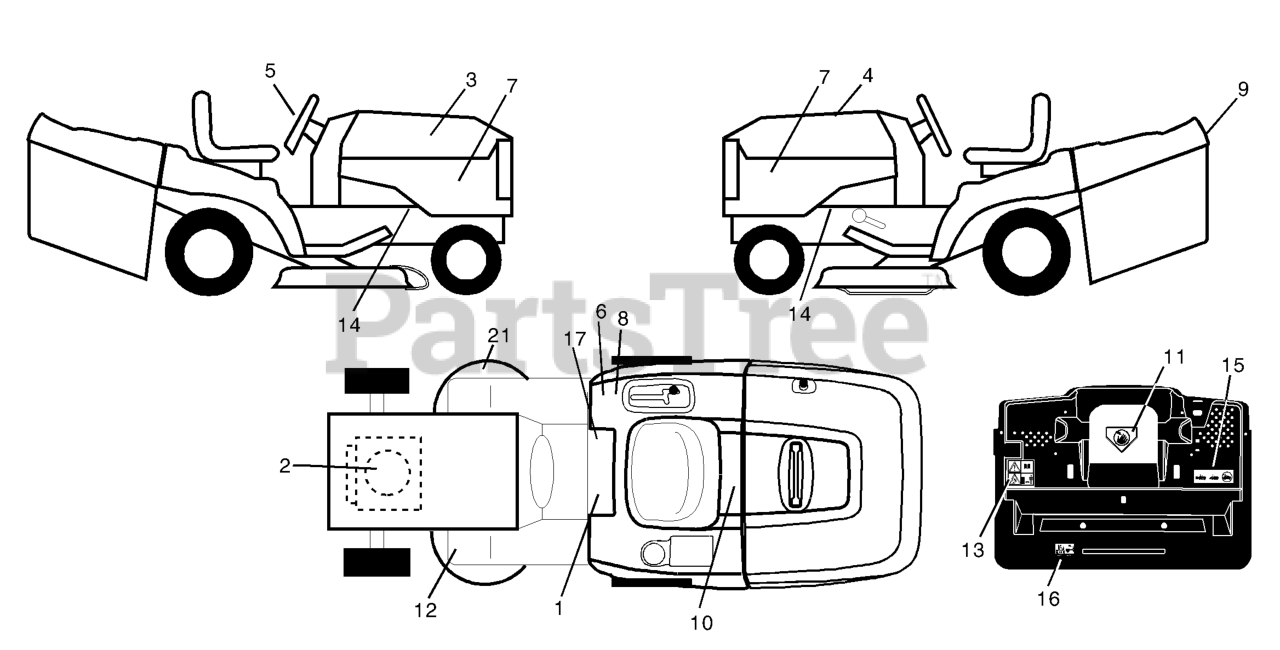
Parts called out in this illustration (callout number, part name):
1	DECAL READ OWNER'S MAN SYMS
2	DECAL HP ENGINE
5	DECAL.WHEEL.STEERING.HUSQ.PERM
6	DECAL CERTIFICATION
7	DECAL PNL SIDE
8	DECAL EUROPE STANDARD CE
9	DECAL FENDER HUSQ
10	DECAL BTRY SYMBOLS
11	DECAL MOWER CUT/FINGER
12	DECAL
13	Decal Warn Back Plate CRD
16	DECAL
17	DECAL PARK BRAKE
